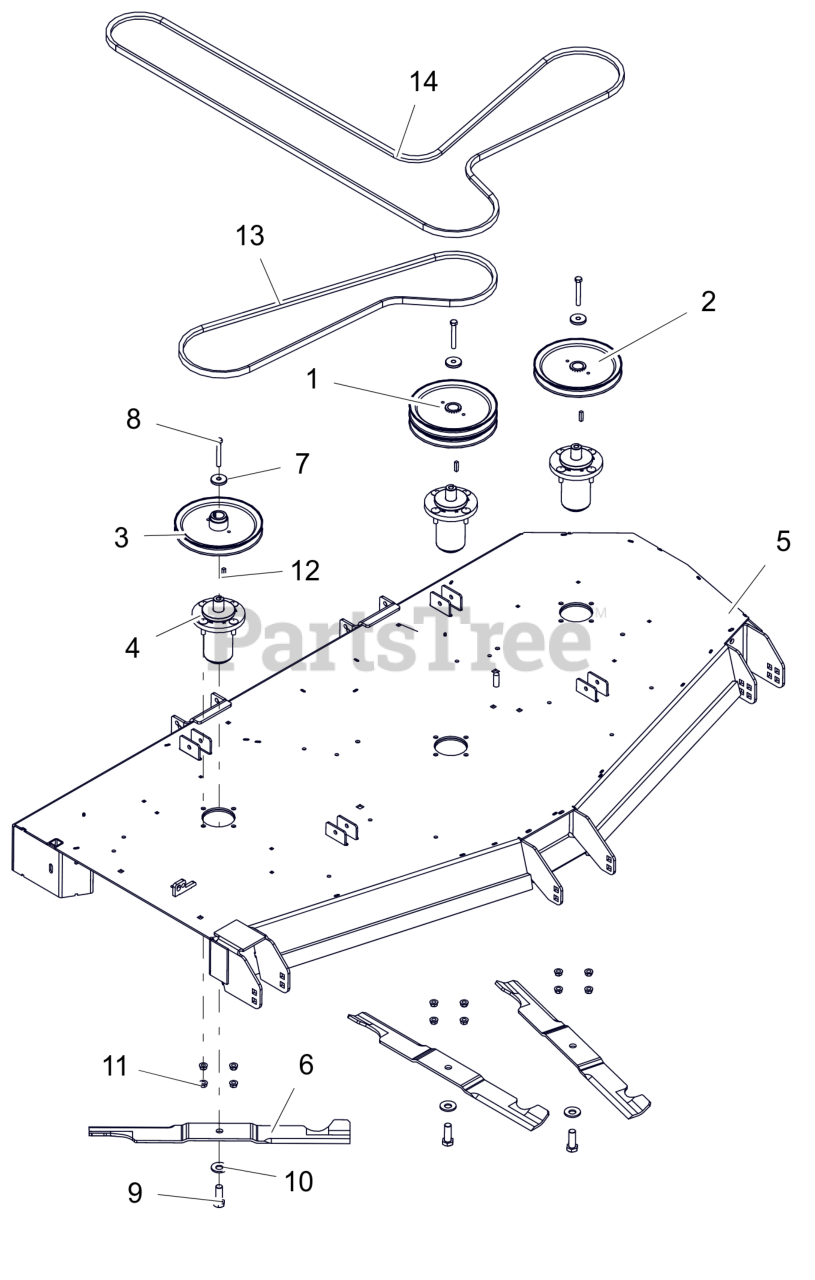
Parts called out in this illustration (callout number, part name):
1	SHEAVE-DOUBLE 1.00"ID X 8.25"OD
2	SHEAVE, SINGLE 1.00" X 8.25" OD
3	SHEAVE, SINGLE 1.00" ID X 8.25" OD
4	ASM, MAINT FREE ALUM SPINDLE
5	WLDMT, 72" SIDE DISCH DECK-X3 (RED) W/ SAFETY DECALS
6	BLADE, 72"
7	RETAINER, SHEAVE
8	BLT, HEX .38-16X2.75 G8 ZCC
9	BLT, HEX .62-18X1.75 G8 ZCC
10	WSHR-BLVL .669X1.535X.138
11	NUT-LK-CTR-FLG .375-16 GF ZCC
12	KEY, SQ .25X.25X1.00 RC 40-50
13	V-BELT, B-COGGED
14	V-BELT, B SECTION
